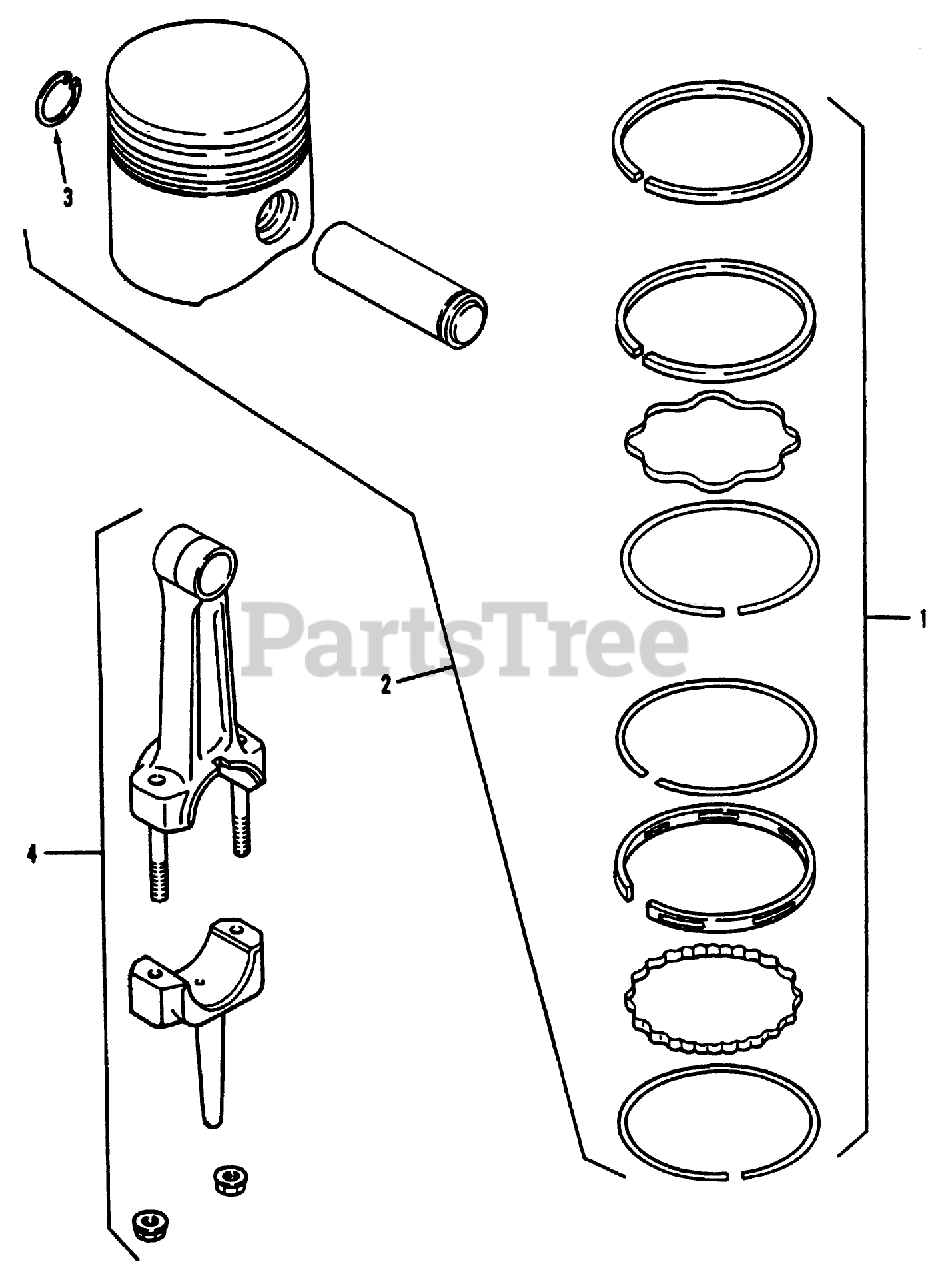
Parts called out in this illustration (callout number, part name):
1	KOHLER 47-108-01
2	KOHLER 47-874-16
3	KOHLER 47-018-01
4	KOHLER 45-067-24
